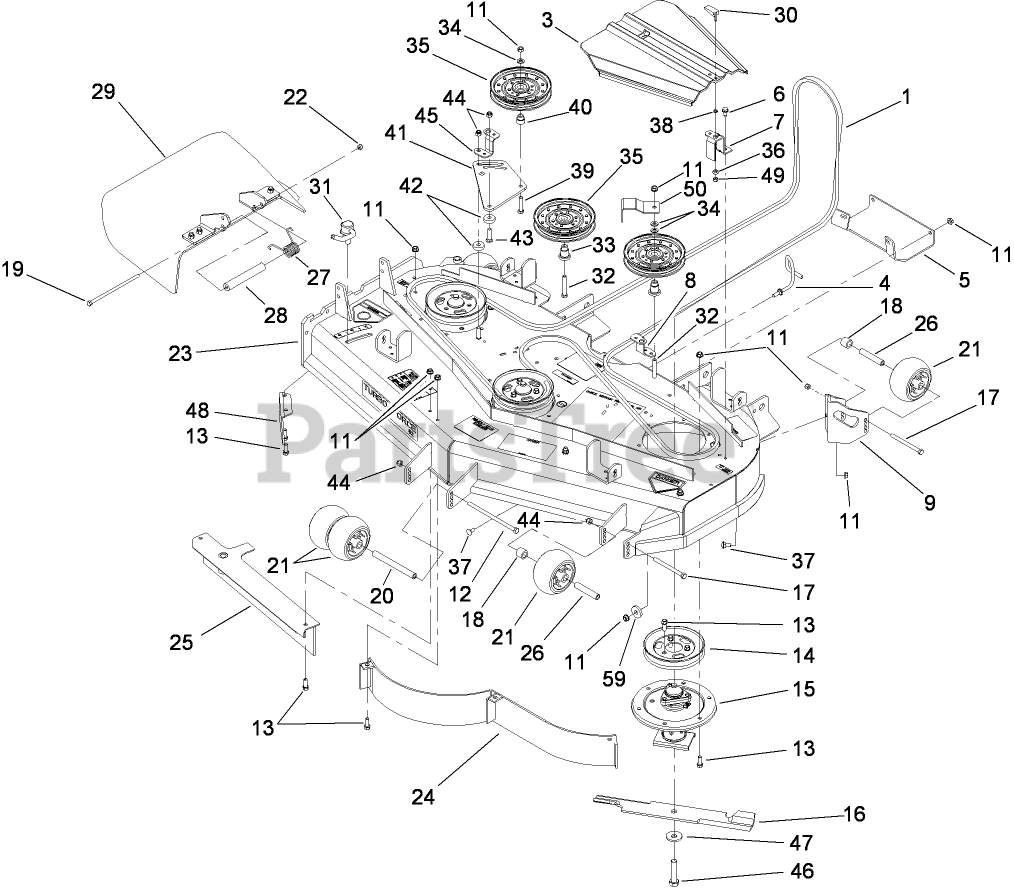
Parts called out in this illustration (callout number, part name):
3	COVER-BELT
4	GUIDE-BELT
5	Plate-Skid
6	SCREW-HWHTF
7	BRACKET-COVER
8	BRACKET-COVER, TALL
9	MOUNT-WHEEL, LH
11	NUT-HHF, WHIZ
12	SCREW-HH
13	SCREW-HWH
14	Pulley
15	SPINDLE ASM
16	BLADE-18IN, HI FLOW
17	SCREW-HH
18	TUBE-SPACER
19	SCREW-HH
20	SPACER-WHEEL
21	ROLLER-SCALP, ANTI
22	NUT-LOCK, NI
23	DECK ASM
26	TUBE-SPANNER
27	SPRING-TORSION
28	SPACER
29	RUBBER DEFLECTOR ASM
30	HANDLE-LATCH, SWELL
31	LEVER ASM
32	SCREW-HH
33	MOUNT-PULLEY
34	WASHER-FLAT
35	Idler-Flat
36	BUSHING-LATCH, SWELL
37	SCREW-CARR
38	WASHER
39	SCREW-HH
40	BUSHING-IDLER
41	Plate-Idler
42	Spacer
43	SCREW-CARR
44	NUT-LOCK, NI
45	BRACKET-COVER, SHORT
46	Screw-Cap
47	Washer-Blade Bolt, Heavy
48	BAFFLE-DISCHARGE
49	NUT-LOCK, HH
50	GUIDE-BELT
59	WASHER
